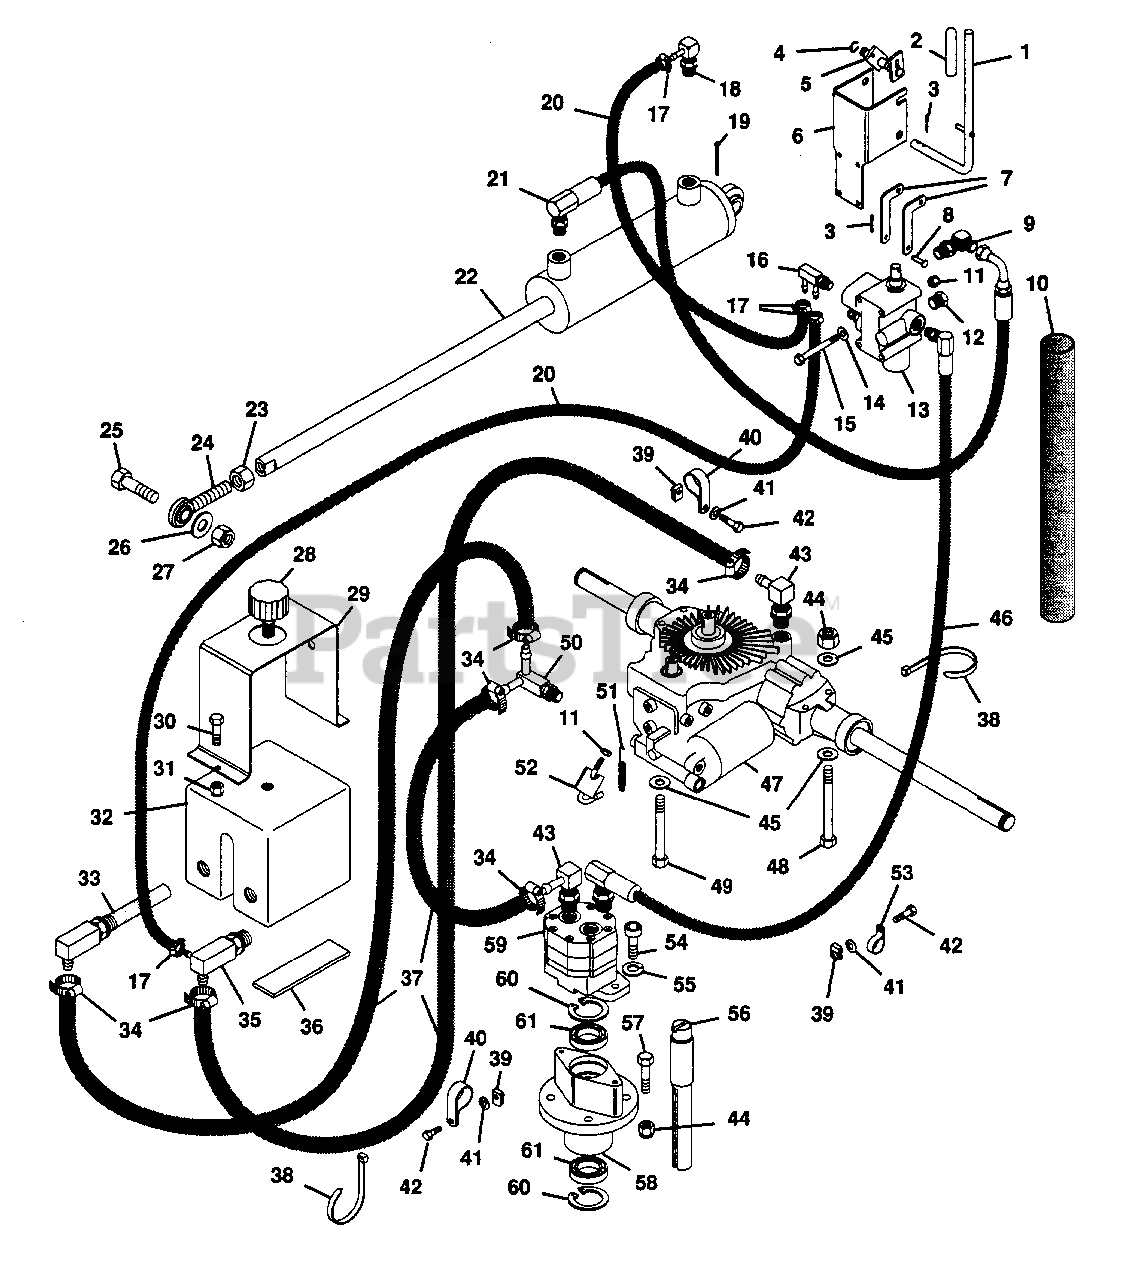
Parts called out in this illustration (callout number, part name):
1	WELDMENT, LEVER
2	GRIP, PTO LEVER
3	PIN, COTTER .094X.75
4	E-RING, 5133-50
5	WELDMENT, LINKAGE
6	BRACKET
7	ROD, HYDRAULIC CONTROL
8	PIN, CLEVIS
9	ADAPTOR, 2503-6-4
10	SLEEVE, PROTECTIVE
11	NUT, LOCK 1/4-20
12	PLUG, PH 05PO-4
13	VALVE, HYDRAULIC
14	WASHER, FLAT .281X.625X.065
15	BOLT, HEX 1/4-20X3.00
16	FITTING
17	CLAMP, HOSE
18	ADAPTOR, 4601-6-6
19	PIN, COTTER .125X1.25
20	HOSE, HYDRAULIC
21	ASSEMBLY, PRESSURE HOSE
22	CYLINDER
23	NUT, JAM 1/2-20
24	ASSEMBLY, ROD END(R.H.)
25	BOLT, HEX 1/2-13X1.75
26	WASHER, FLAT .531X1.062X.095
27	NUT, LOCK 1/2-13
28	CAP, FILTER
29	STRAP, TANK
30	BOLT, HEX 5/16-18X.75
31	NUT, LOCK 5/16-18
32	TANK, HYDRAULIC
33	FITTING, FILTER
34	CLAMP, .88 DIA. HOSE
35	FITTING
36	PAD, GAS TANK
37	HOSE, HYDRAULIC
38	TIE WRAP, BLACK
39	NUT, RETAINER
40	CLAMP, STEEL 1.00
41	WASHER, LOCK 1/4 REG.
42	BOLT, HEX 1/4-20X.875
43	FITTING
44	NUT, LOCK 3/8-16
45	WASHER, FLAT .406X.812X.065
46	ASSEMBLY, PRESSURE HOSE
47	FILTER, OIL
48	BOLT, HEX 3/8-16X3.50
49	BOLT, HEX 3/8-16X3.00
50	FITTING
51	SPRING, PTO RETURN
52	WELDMENT, LEVER
53	CLAMP, STEEL .625
54	SCREW, CAP 3/8-16 HSHD
55	WASHER, LOCK 3/8 REG.
56	SHAFT
57	BOLT, HEX 3/8-16X1.25
58	HOUSING
59	PUMP, HYDRAULIC
60	RING, BEARING 2.000 BORE
61	BEARING, BALL 1.000X2.000X.562
